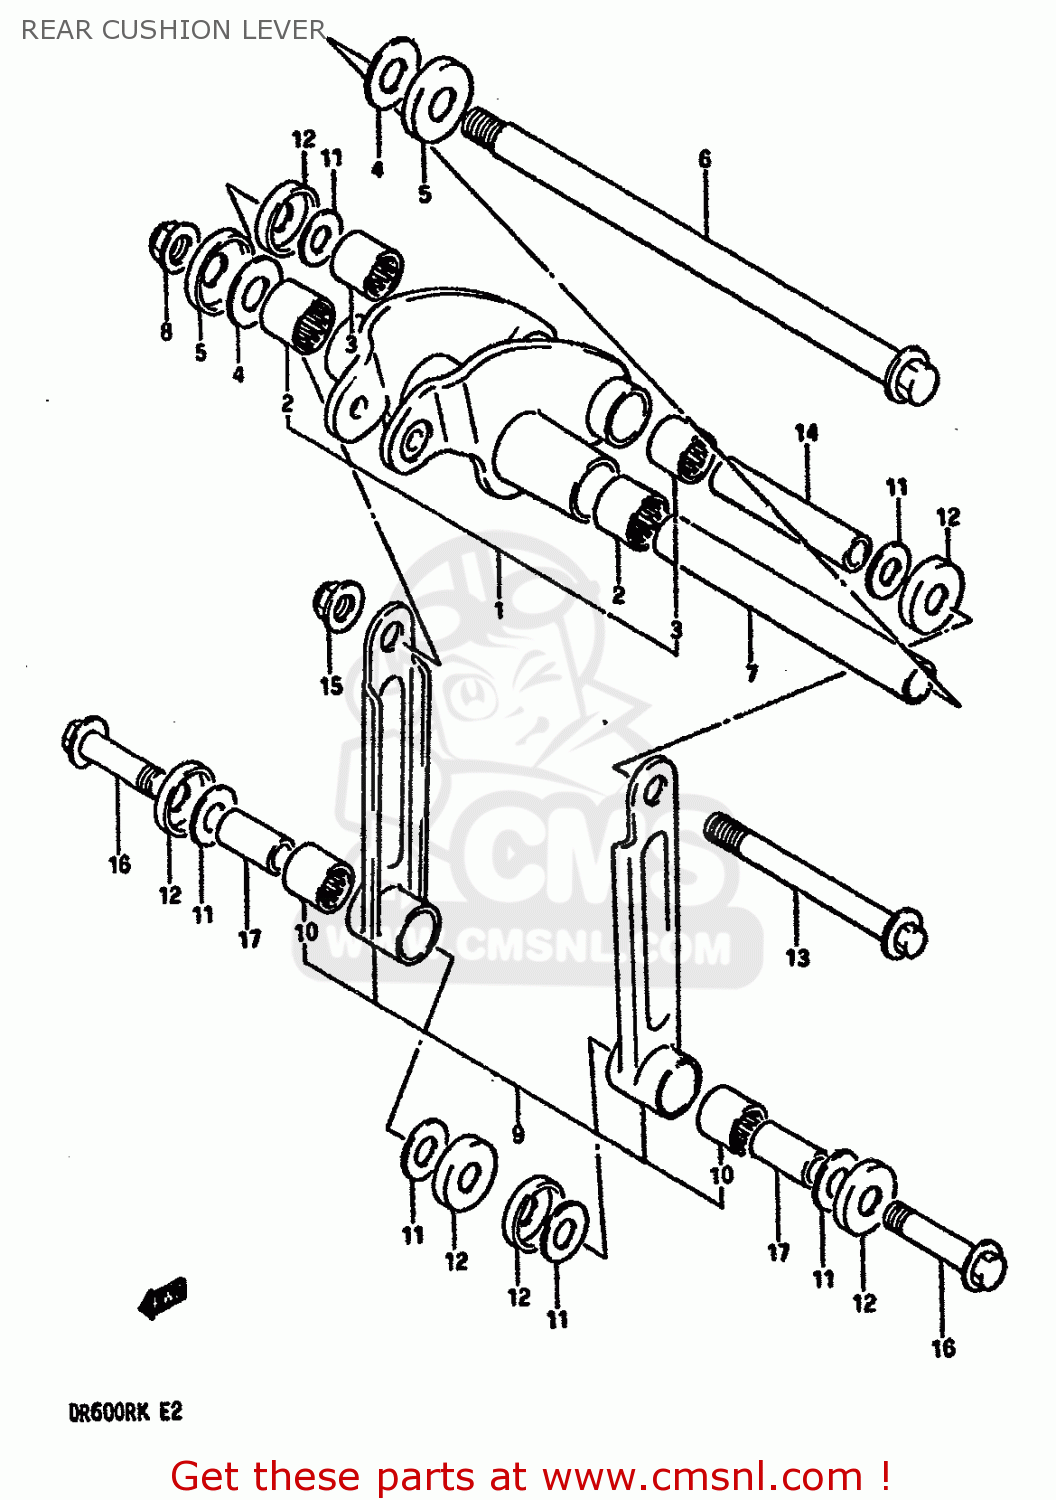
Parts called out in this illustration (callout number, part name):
1	LEVER SET,REAR CUSHION
2	BEARING(20X27X25)
3	ROLLER BEARING (17X24X25)
4	WASHER
5	SEAL,REAR CUSHION LEVER
6	SHAFT,REAR CUSHION LEVER
7	SPACER,RR CUSHION LEVER
8	NUT 12MM
9	ROD SET,REAR CUSHION
10	ROLLER BEARING (17X24X25)
11	WASHER
12	COVER,RR SWGARM DUST SEAL
13	BOLT,REAR CUSHION ROD
14	SPACER,RR CUSHION ROD UPR
15	NUT 12MM
16	RING,BEARING STOPPER
17	SPACER,RR CUSHION ROD LWR
